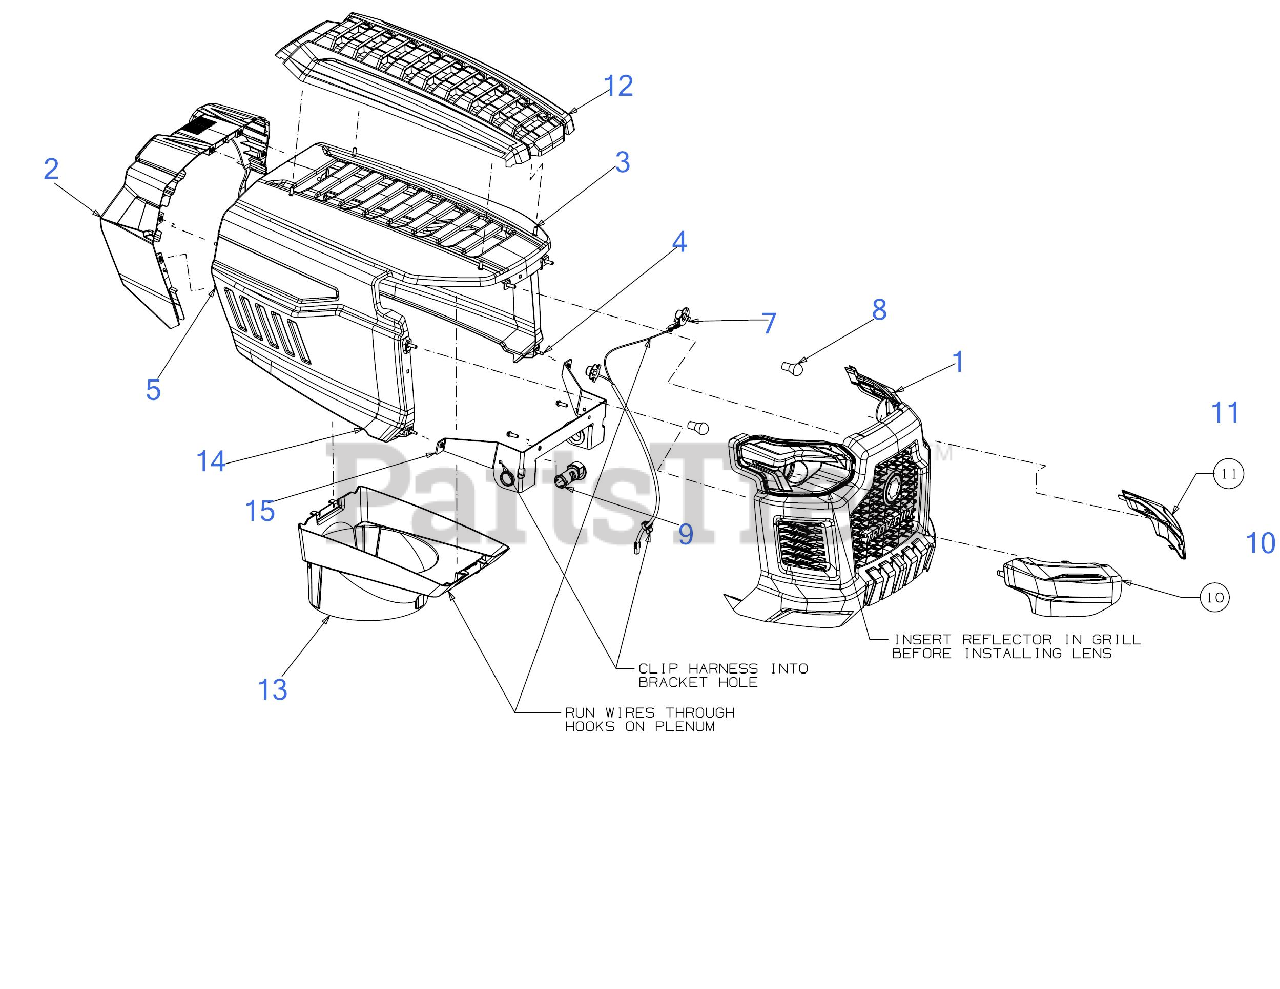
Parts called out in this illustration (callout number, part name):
1	FRONT GRILLE
3	SCREW 1/4 x .750
4	SCREW M6-1 x .625
5	SCREW 1/4-20X.5 GR5
7	HEADLIGHT HARNESS
8	MINIATUURE BULB 12V
9	HOOD PIVOT PIN
10	HEADLIGHT LENS (RH)
11	HEADLIGHT LENS (LH)
12	HOOD SCOOP
13	HOOD PLENUM (B STYLE)
